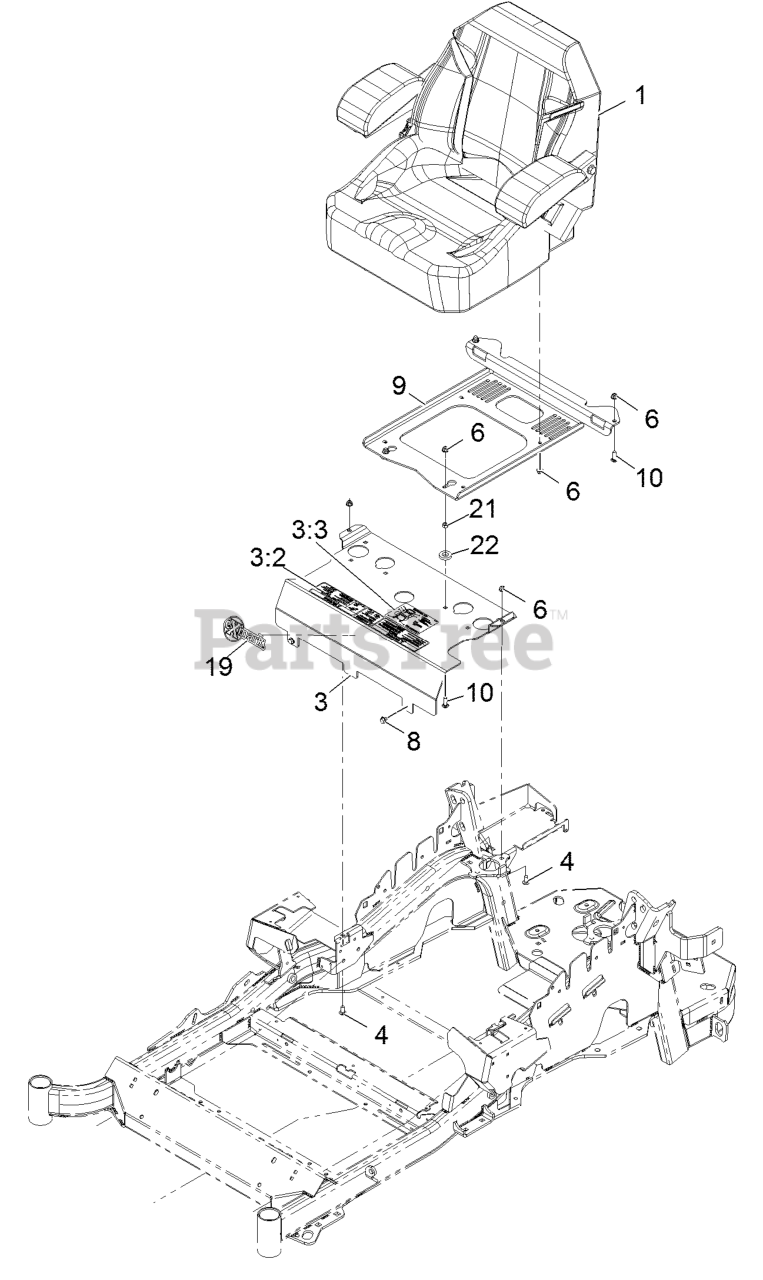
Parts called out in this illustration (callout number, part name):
3	MOUNT-SEAT
3:2	DECAL-CONSOLE
3:3	DECAL-SERVICE AID
4	SCREW-CARR
6	NUT-HF, NI
9	PLATE-SUPPORT, SEAT
10	SCREW-CARR
21	NUT-HEX
